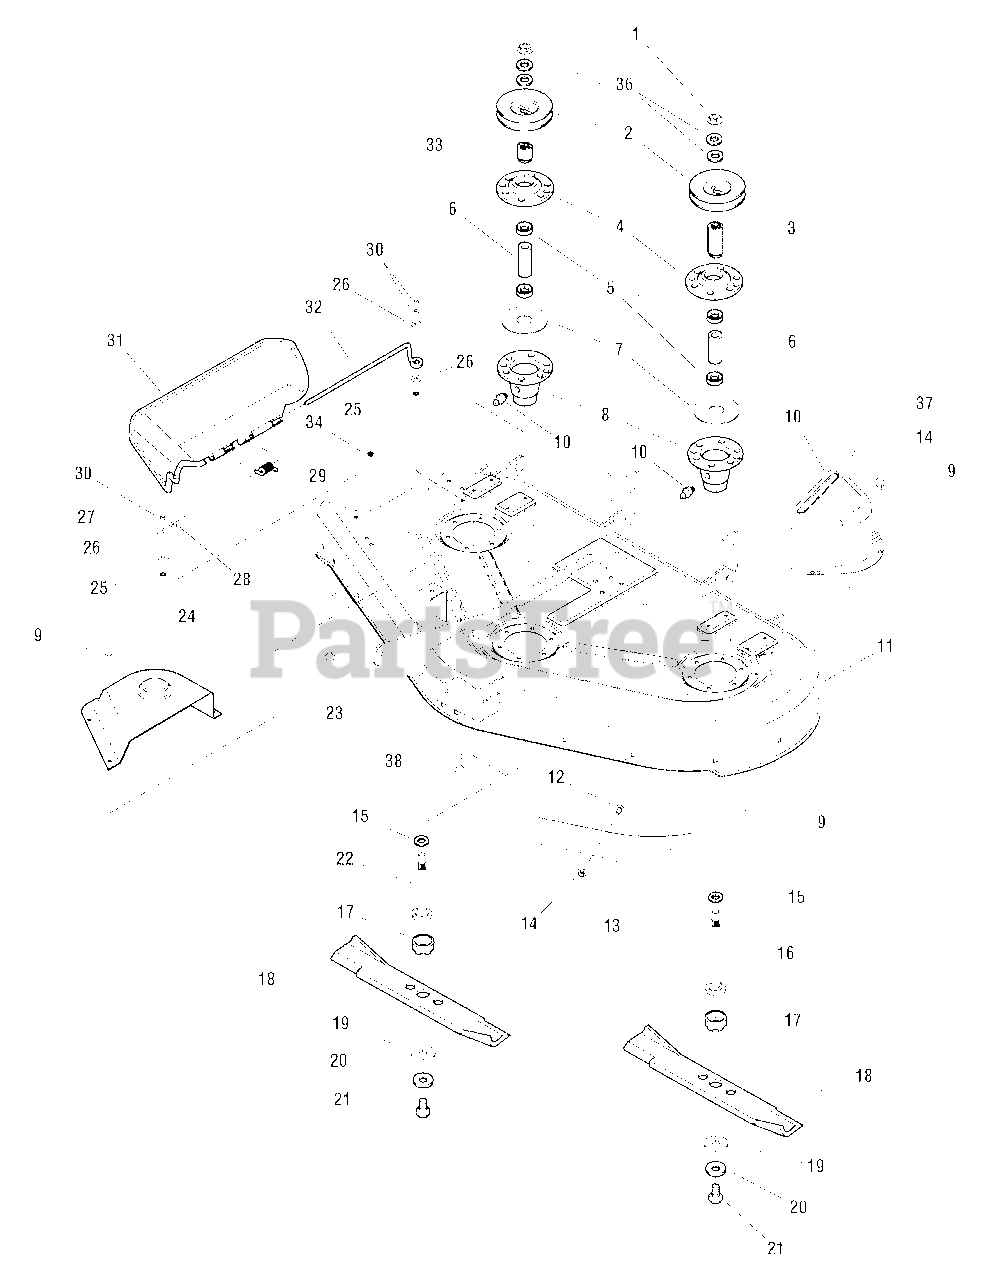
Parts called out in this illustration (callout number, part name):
1	NUT, Hex Flange 9/16-18
2	PULLEY, .68" Deep-Groove Pulley
3	HUB
4	HOUSING, Arbor Top
5	BEARING, Ball 11/16 x 9/16 x 15/32
6	SPACER, Powdered Metal
7	GASKET
8	HOUSING, Arbor Bottom w/Lube Fitting
9	SCREW-HEX WSHR HD TAPTT5/16-18X0.750BLK
10	COVER, Arbor
11	HOUSING ASSEMBLY, 50" (Orange)
11	HOUSING ASSEMBLY, 50" (Red)
12	CARRIAGE BOLT, 5/16-18 x 3/4 G5
13	BAFFLE, Blowout, Short
14	NUT, Hex Flange 5/16-18, Whiz Lock Small
15	WASHER, Cup
16	SHAFT, Arbor
17	SHIELD, Grass Lower Arbor, Heat Treated
18	BLADE, Mower
19	WASHER, Hex 11/16 x 2
20	WASHER, Spring
21	CAPSCREW, Hex Head 7/16-14 x 1-1/4 G8
22	SHAFT, Arbor
23	CARRIAGE BOLT, 1/4-20 x 1 G5
24	COVER, Arbor
25	NUT, Push for 1/4 Diameter Thread
26	WASHER, 1/4
27	CLAMP, Wire
28	WASHER, 5/16
29	SPRING, Torsion, Chute
30	NUT, Hex Lock ESNA Light 1/4-20
31	DEFLECTOR
32	ROD, Deflector
33	HUB
34	PLUG
36	WASHER, Bellville
37	SCREW, Hex Head Serange Flange Taptite 5/16-18 x 2
38	CARRIAGE BOLT, 1/4-20 x 1-1/2 G5
